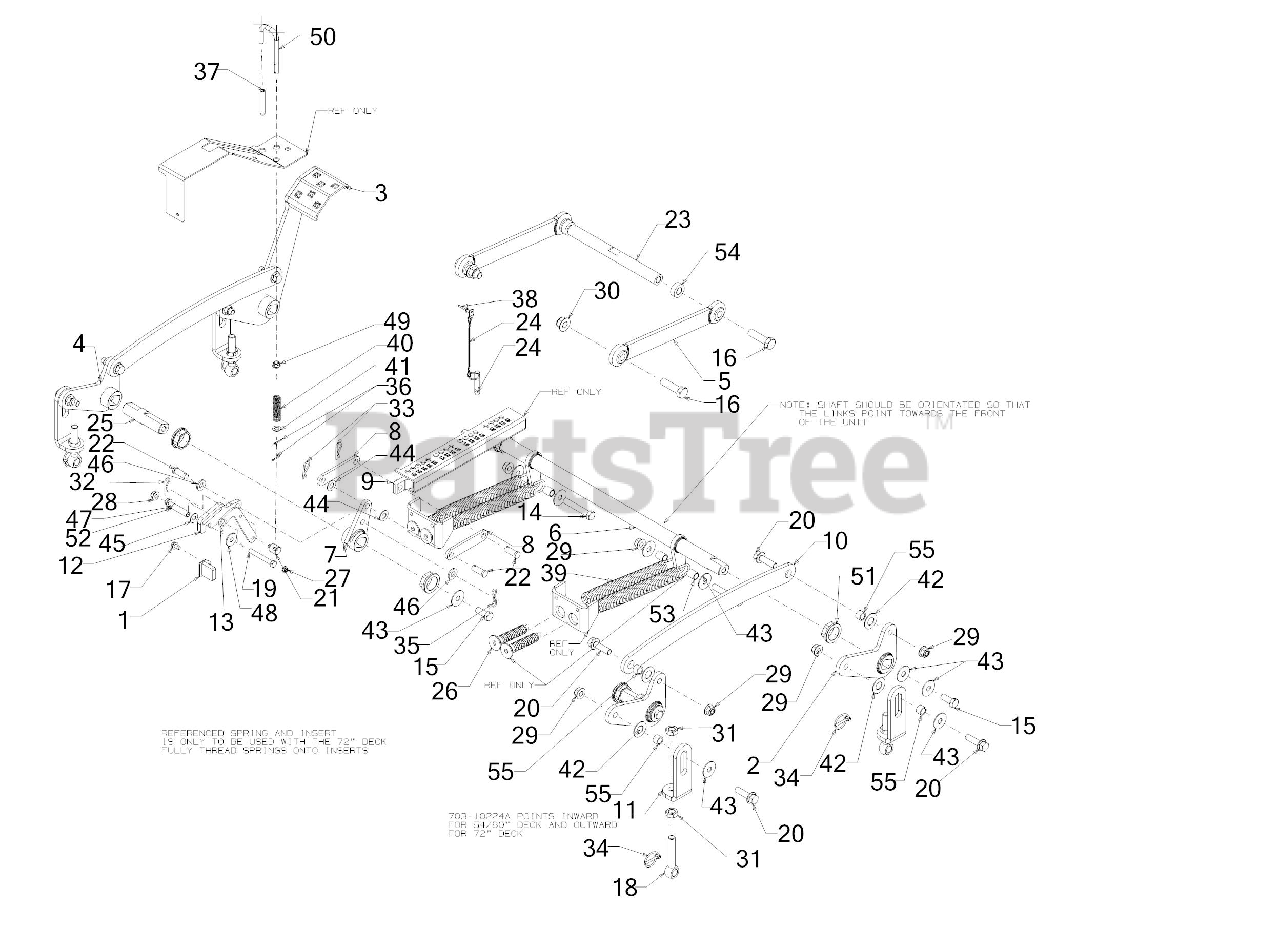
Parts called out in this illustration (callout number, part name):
6	FRONT DECK LIFT SHAFT
7	DECK LIFT HUB ASSEMBLY (LH)
8	DECK LIFT LINK
9	DECK LIFT LINK
13	PIVOT LOCKOUT LINK
14	HEX SCREW 1/2-13 x 3.00
15	SCREW 1/2-13 x 1.25 GR5
16	SCREW 5/8-11 x 2.25 GR5
17	SCREW 5/16-18 x .500
18	EYE BOLT 5/8-11 X 3.63
19	SCREW 3/8-16 x 2.75 GR5
20	BOLT-1/2-13X1.75LG
21	BRAKE FERRULE
22	CLEVIS PIN .500 x 1.25
23	FRONT LIFT SHAFT
24	DETENT PIN
25	LIFT SHAFT (LH)
26	SPRING INSERT SCREW
27	FLANGE LOCK NUT
30	FLANGE LOCK NUT
31	HEX NUT
32	INTERNAL COTTER PIN
33	COTTER PIN
35	PIN:COTTER
36	COTTER PIN 3/32
38	FULL TUBULAR RIVET
39	EXTENTION SPRING 1.20 x 11.35
40	COMPRESSION SPRING .656 ODX 2.445"
41	FLAT WASHER
42	FLAT WASHER .760ID X1.49OD x .06
43	WASHER .51 x 1.5 x .07
44	FLAT WASHER .510 x 1.00 x .060
45	FLAT WASHER
46	FLAT WASHER .510 x 1.000 x .125
47	SHOULDER SCREW
48	SHOULDER SPACER
49	BUSHING .380 ID
50	DECK LOCK OUT ROD
51	FLANGE BEARING
53	SPACER 0.535 X 0.68 X 0.83
